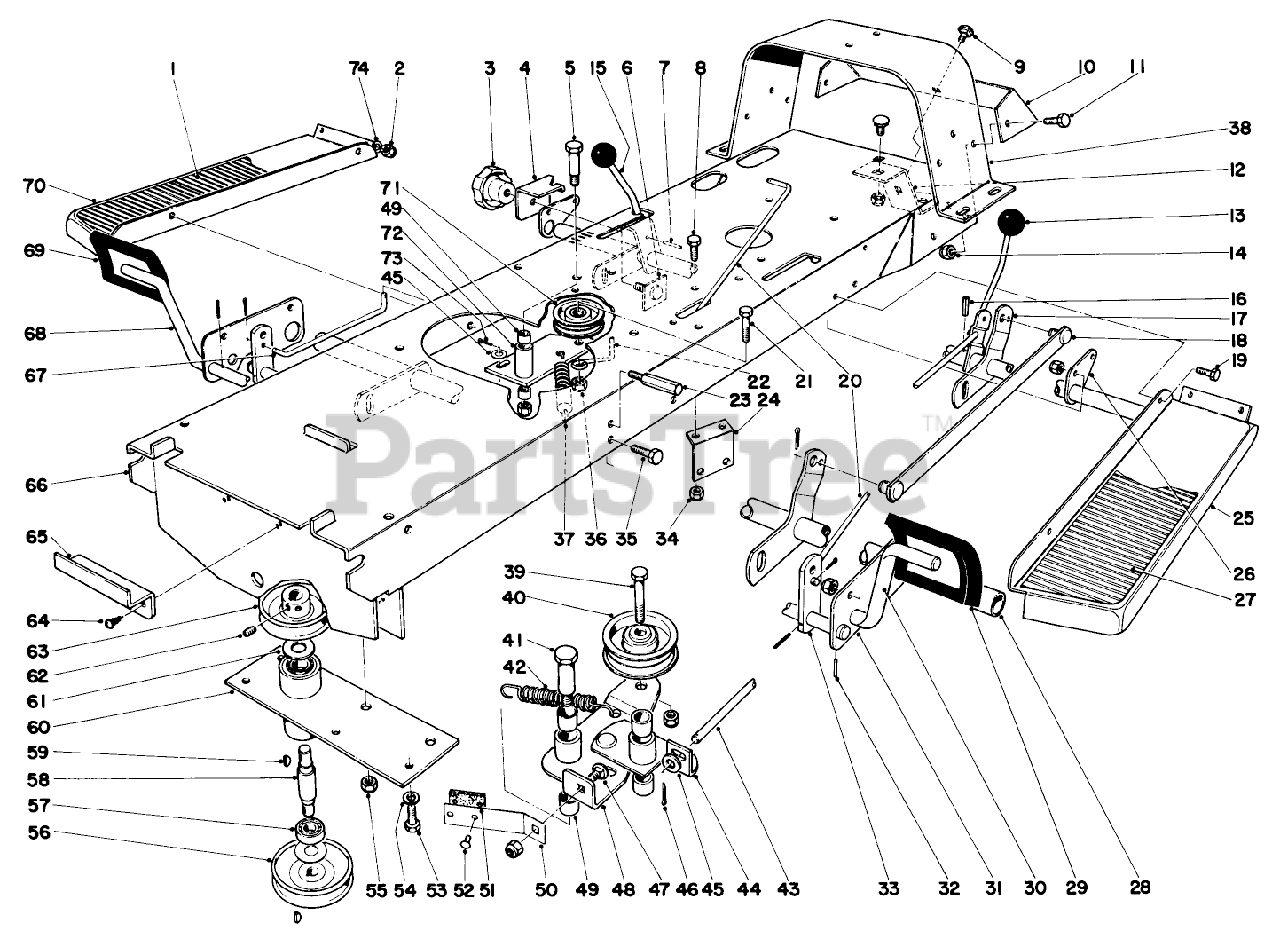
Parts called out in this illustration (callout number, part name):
1	Foot Pad
2	NUT-HEX
4	Slide Height Adj.
5	Shoulder Bolt
6	Knob Plate
7	PIN-ROLL
8	SCREW-HH
9	SCREW-CARR
10	Frame Member Rear
11	SCREW-HH
12	Bracket Hitch
13	Knob
15	Rod Control Hgt. Adj.
16	1/8 X 1-3/8 ROLL PIN
17	Rear Height Adj. Tube
18	Height Adj. Link
19	SCREW-HH
20	Brake Rod
21	SCREW-HH
22	Belt Retainer
23	Pedal Stop
24	Belt Guide
25	Footrest
26	Bracket Tube
27	Foot Pad L.H.
28	Front Height Adj. Tube
29	CLUTCH PAD
30	Clutch Pedal
31	Plate Tube
32	PIN-SPRING
33	Arm Lever
34	Nut
35	SCREW-HH
37	Spring
38	Rear Support
39	SCREW-HH
40	Pulley
41	Shoulder Bolt
42	Spring
43	Clutch Rod Blade
44	Pivot Bracket
45	WASHER-FLAT
46	PIN-COTTER
47	SCREW-CARR
48	Idler Plate
49	Bushing
50	Clutch Brake
51	BLADE BRAKE LINING
53	SCREW-HH
54	WASHER-LOCK
56	Pulley
57	Bearing
58	Pulley Shaft
59	KEY-WOODRUFF
60	Pulley Tube
61	Bearing Washer
62	SCREW-SET, HSH
63	Pulley
64	10-32 X 1/2 PHILLIPS
65	Spring Clip
66	Frame
67	Clutch Rod
68	Brake Pedal
69	PAD-BRAKE
70	Footrest
71	Pulley
72	Idler Arm
73	PIN-COTTER
74	WASHER-PLAIN
